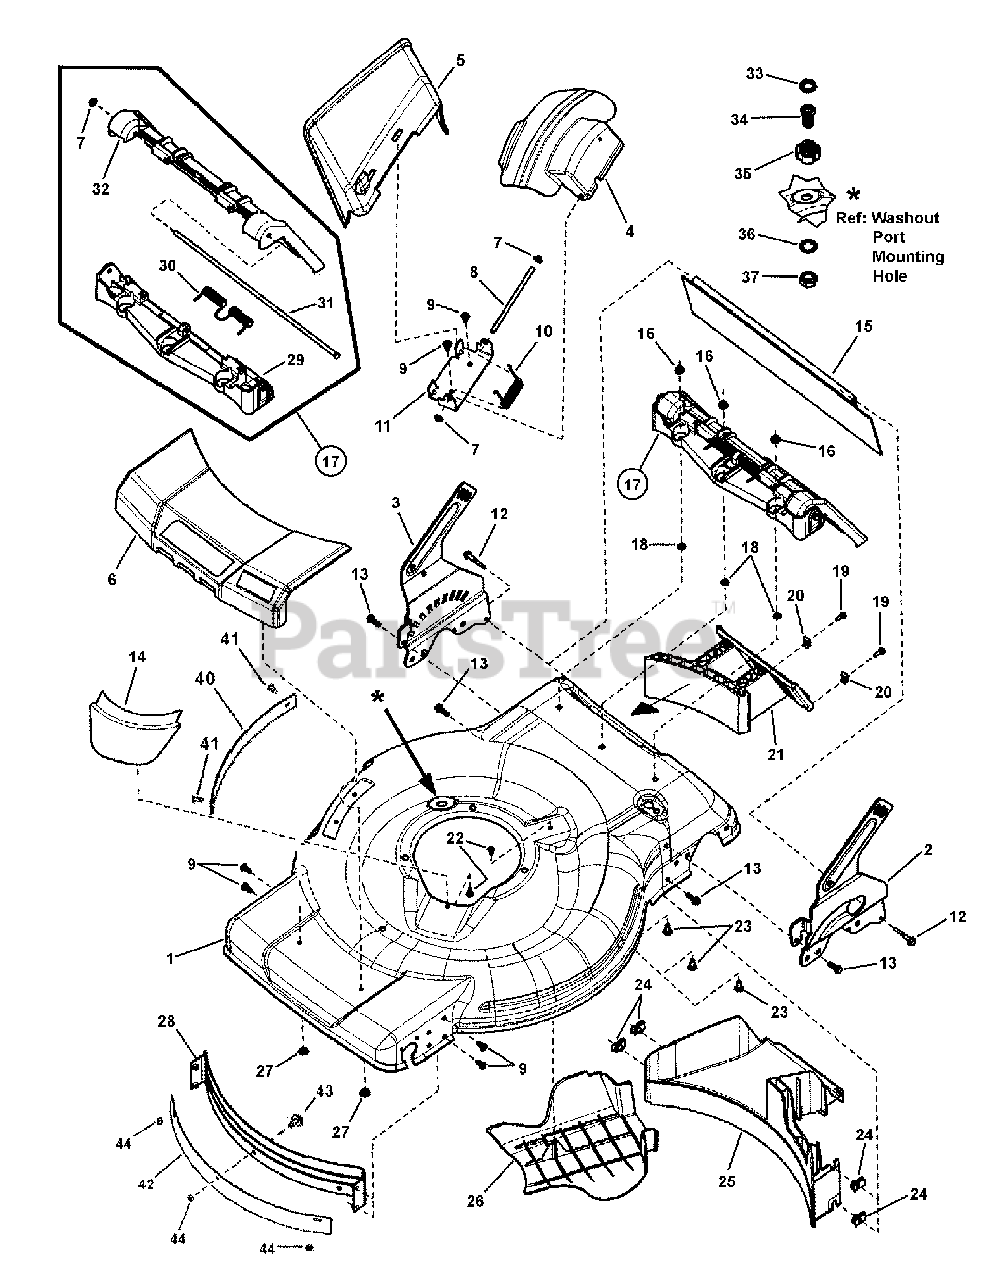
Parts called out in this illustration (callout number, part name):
1	DECK, 22", Rear Wheel Drive, Washout
2	BRACKET, Lower Handle, LH, 22 WBM
3	BRACKET, Lower Handle, RH, 22 WBM
3	BRACKET, Lower Handle, Elec HOC, RH
4	COVER, Mulching
5	CHUTE, Side Discharge, 22" WBM
6	COVER, Front, Push/Rear Wheel Drive
7	PUSHNUT, 1/4"
8	ROD, Pivot
9	SCREW, 1/4-20 x .550 Self-Tap (Torx)
10	SPRING, Torsion, Chute
11	BRACKET, Chute
12	BOLT, 1/4-20 x 1-1/2" Shoulder
13	BOLT, 1/4-20 x 3/4" Hex Flange Lock, GR 5
14	DEBRIS SHIELD, Front
15	GUARD, Rear 22"
16	NUT, 1/4-20 Hex Flange Lock
17	ASSEMBLY, Door, 22" WBM
18	BOLT RETAINER, 1/4"
19	SCREW, #10-24 x 5/8" Hex Washer Face Self-Tap, GR 5
20	NUT, #10-24 Retainer Speed w/extrusion
21	PLUG, Mulching, 22" Deck
22	SCREW, Round Washer Head Torx, Hi-Lo
23	BOLT, 1/4-20 x 5/8" Flat Head Square Neck, GR 5
24	U-NUT, 1/4-20
25	BAFFLE, Rear, Rear Wheel Drive WBM
26	BELT COVER, Rear Drive
27	NUT, 3/16" Push
28	BAFFLE, Front
29	HINGE, Rear Discharge Door
30	SPRING, Torsion, Rear Door
31	ROD, Pivot, Rear Door
32	DOOR, Rear Discharge
33	WASHER, Hose
34	ADAPTOR, Washout Port, WBM
35	COUPLING, Hose
36	WASHER, 5/8" Internal Tooth Lock YZ
37	NUT, 5/8-11, NC-2B Black Hex Jam
40	PLATE, Side Discharge Extension, Galv.
41	POP RIVET, 3/16 X .063 - .125
42	EXTENSION, Baffle, 22", EURO, Galv.
43	SCREW, #10-24 X 1/2, Hex Washer Self-Tap, BZ
44	NUT, 10-24, Hex Center Lock, BZ
